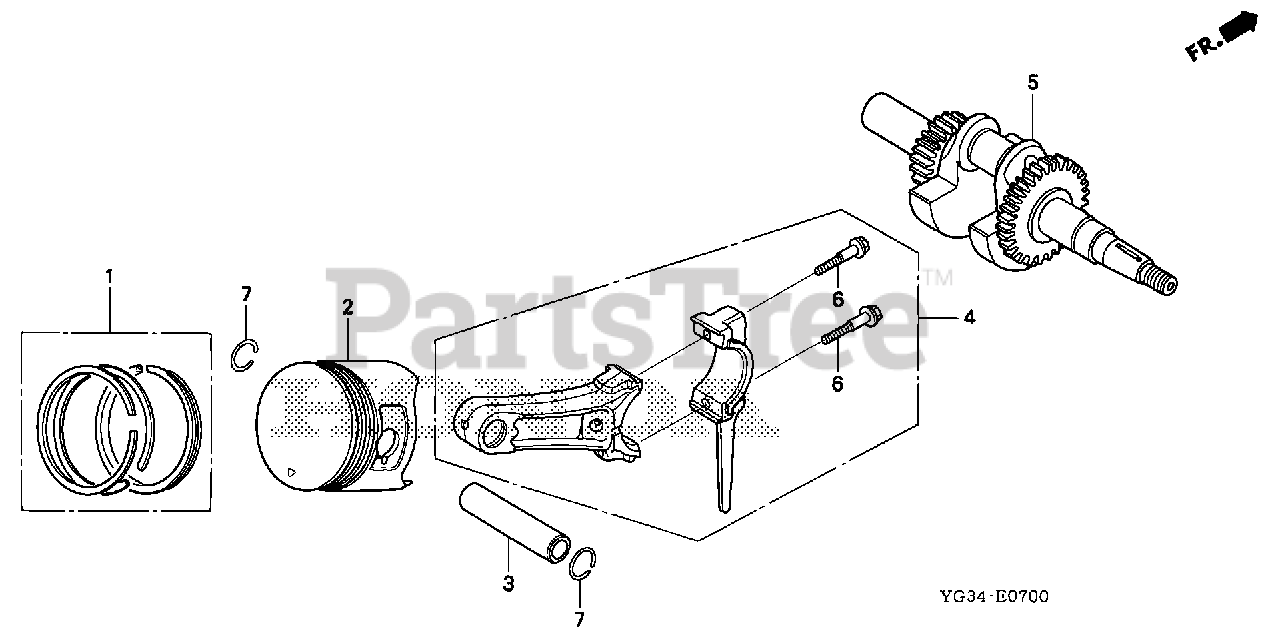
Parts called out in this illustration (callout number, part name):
1	RING SET, PISTON (STD) (TEIKOKU)
1	RING SET, PISTON (STD) (RIKEN)
1	RING SET, PISTON (0.25) (TEIKOKU)
1	RING SET, PISTON (0.25) (RIKEN)
1	RING SET, PISTON (0.50) (TEIKOKU)
1	RING SET, PISTON (0.50) (RIKEN)
1	RING SET, PISTON (0.75) (TEIKOKU)
1	RING SET, PISTON (0.75) (RIKEN)
2	PISTON (STD)
2	PISTON (0.25)
2	PISTON (0.50)
2	PISTON (0.75)
3	PIN, PISTON
4	ROD ASSY., CONNECTING
4	ROD ASSY., CONNECTING (UNDER SIZE)
5	CRANKSHAFT
6	BOLT, CONNECTING ROD
7	CLIP, PISTON PIN (13MM)
